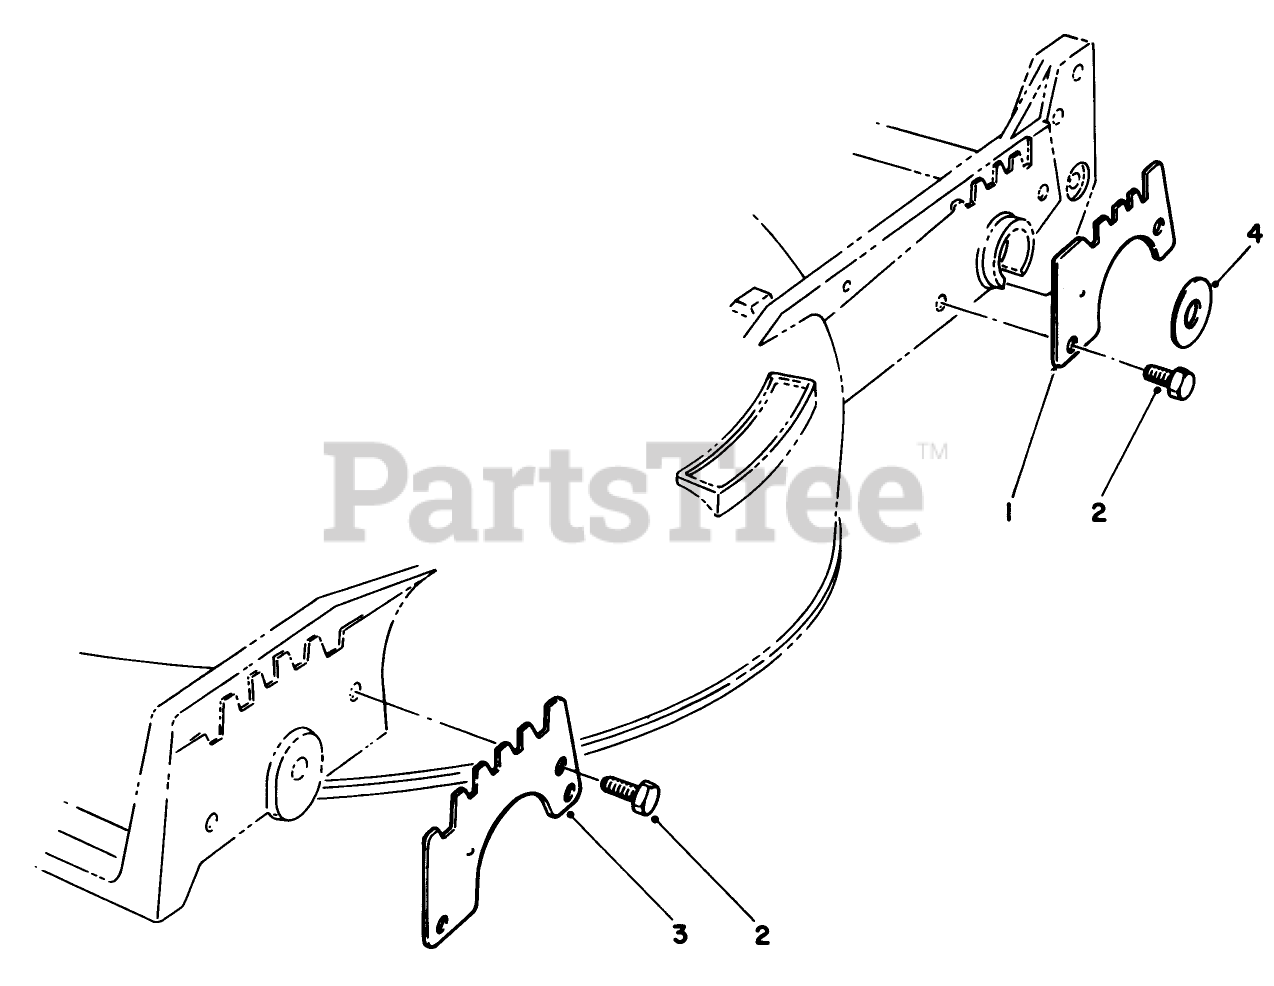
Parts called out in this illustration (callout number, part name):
1	WEAR PLATE,REAR
2	SCREW-HWH
3	WEAR PLATE
4	PIVOT WASHER
